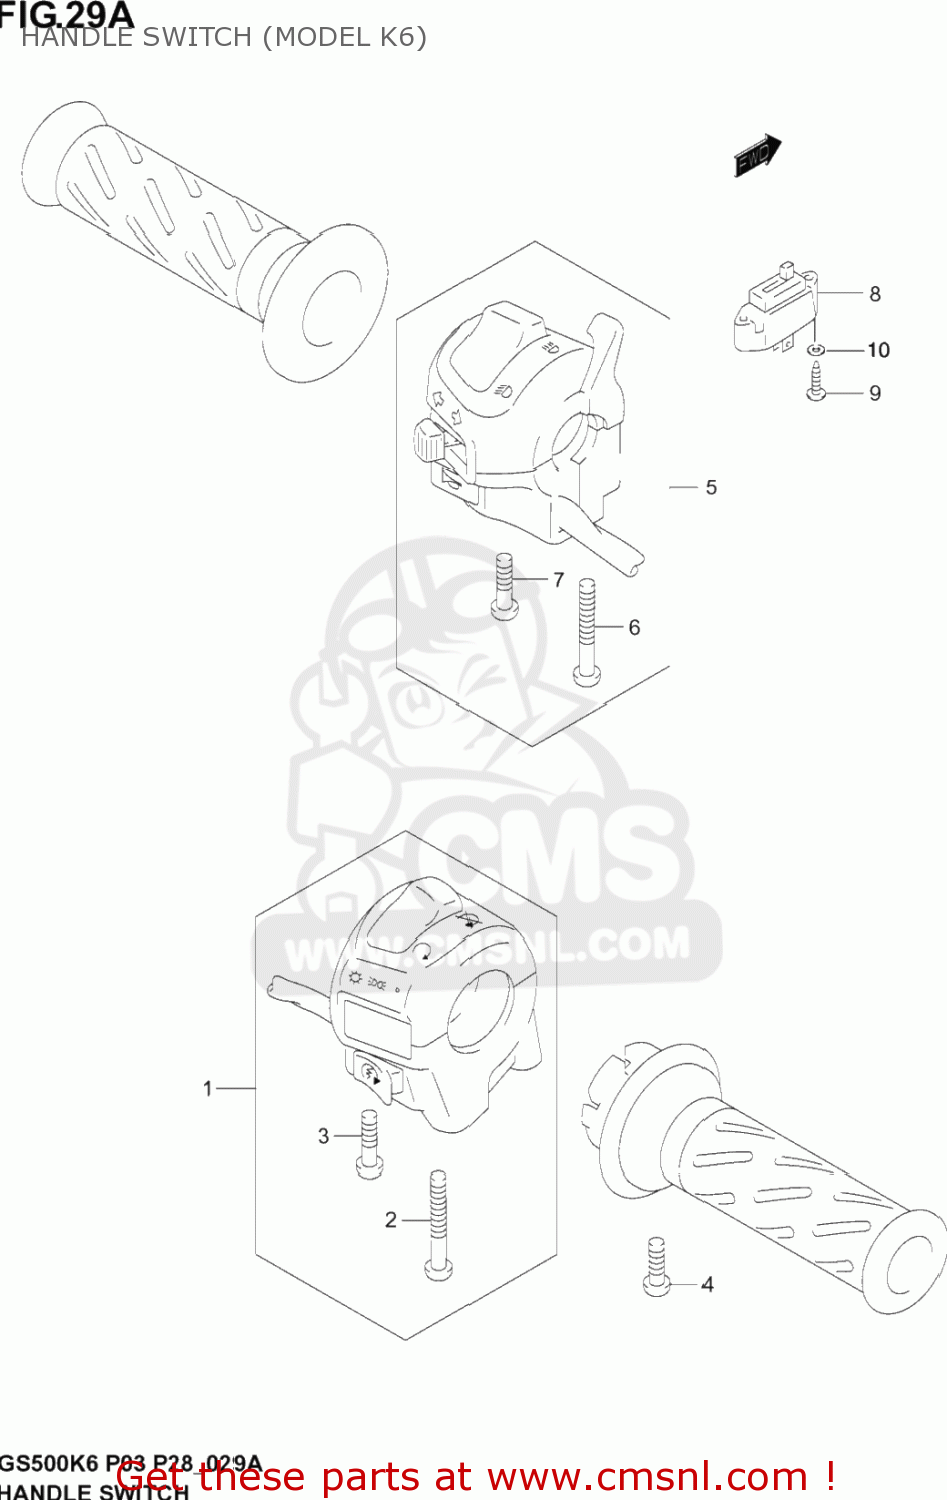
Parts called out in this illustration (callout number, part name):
1	SWITCH ASSY,HA
2	SCREW
3	SCREW
4	SCREW
5	SWITCH ASSY,HANDLE,L
6	SCREW, 5X45
7	SCREW(5X25)
8	SWITCH ASSY,CLUTCH
9	SCREW(3X14)
10	WASHER
